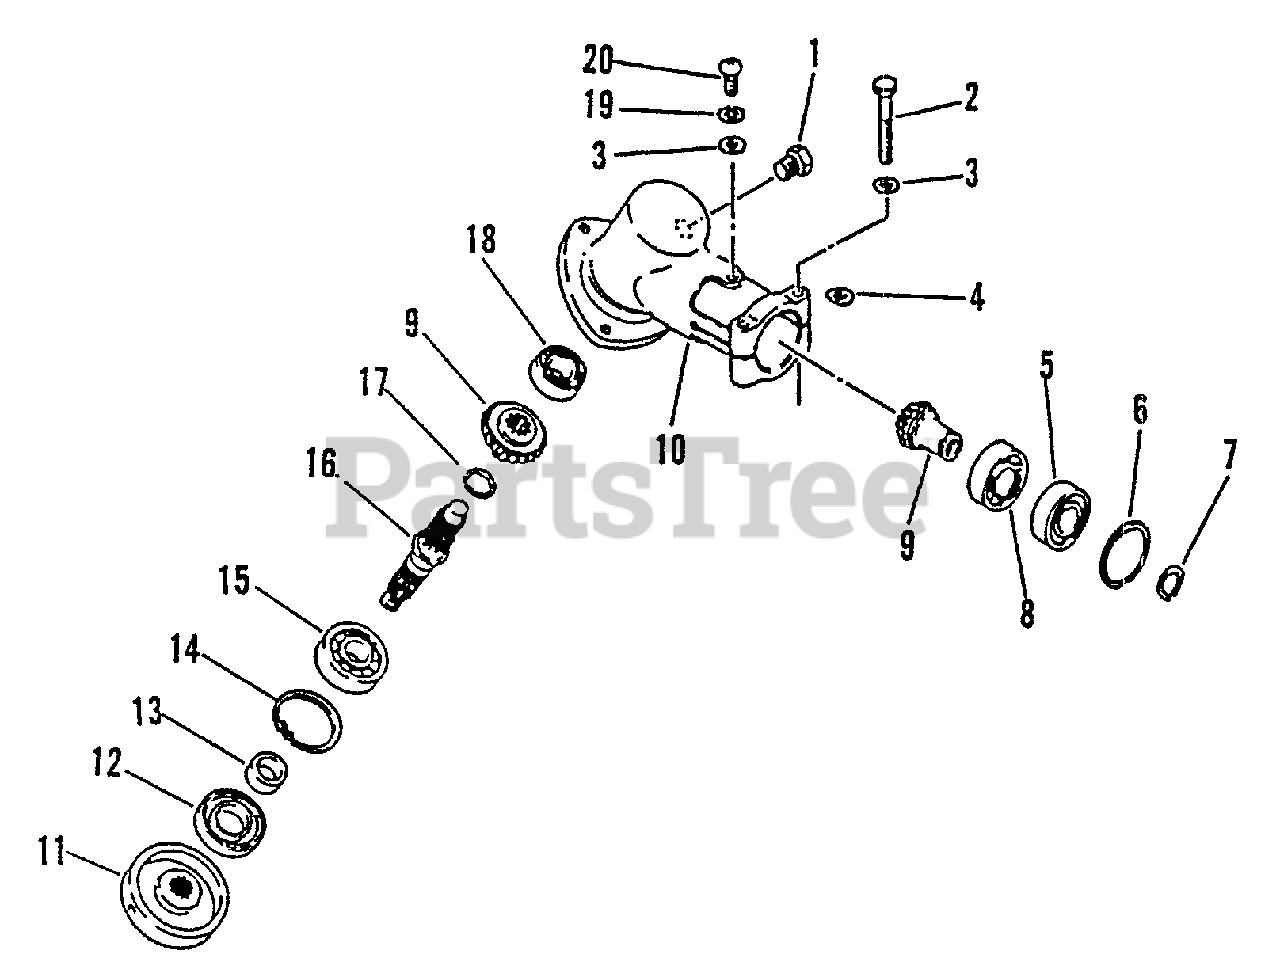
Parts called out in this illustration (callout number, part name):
1	BOLT - 8X8
2	BOLT - 5X35
3	WASHER - 5
5	BEARING, BALL - 6900Z
6	RING, RETAINING - 22
7	RING, RETAINING - 12
8	BEARING, BALL - 6900
9	GEAR SET - BEVEL
10	CASE, GEAR
11	ADAPTOR, BLADE - UPPER
12	SEAL, OIL
14	RING, RETAINING - 32
15	BEARING, BALL - 6201
16	GEAR - SHAFT
17	RING, RETAINING - 10
18	BEARING, BALL - 609
19	LOCKWASHER - 5
20	SCREW - 5X10
